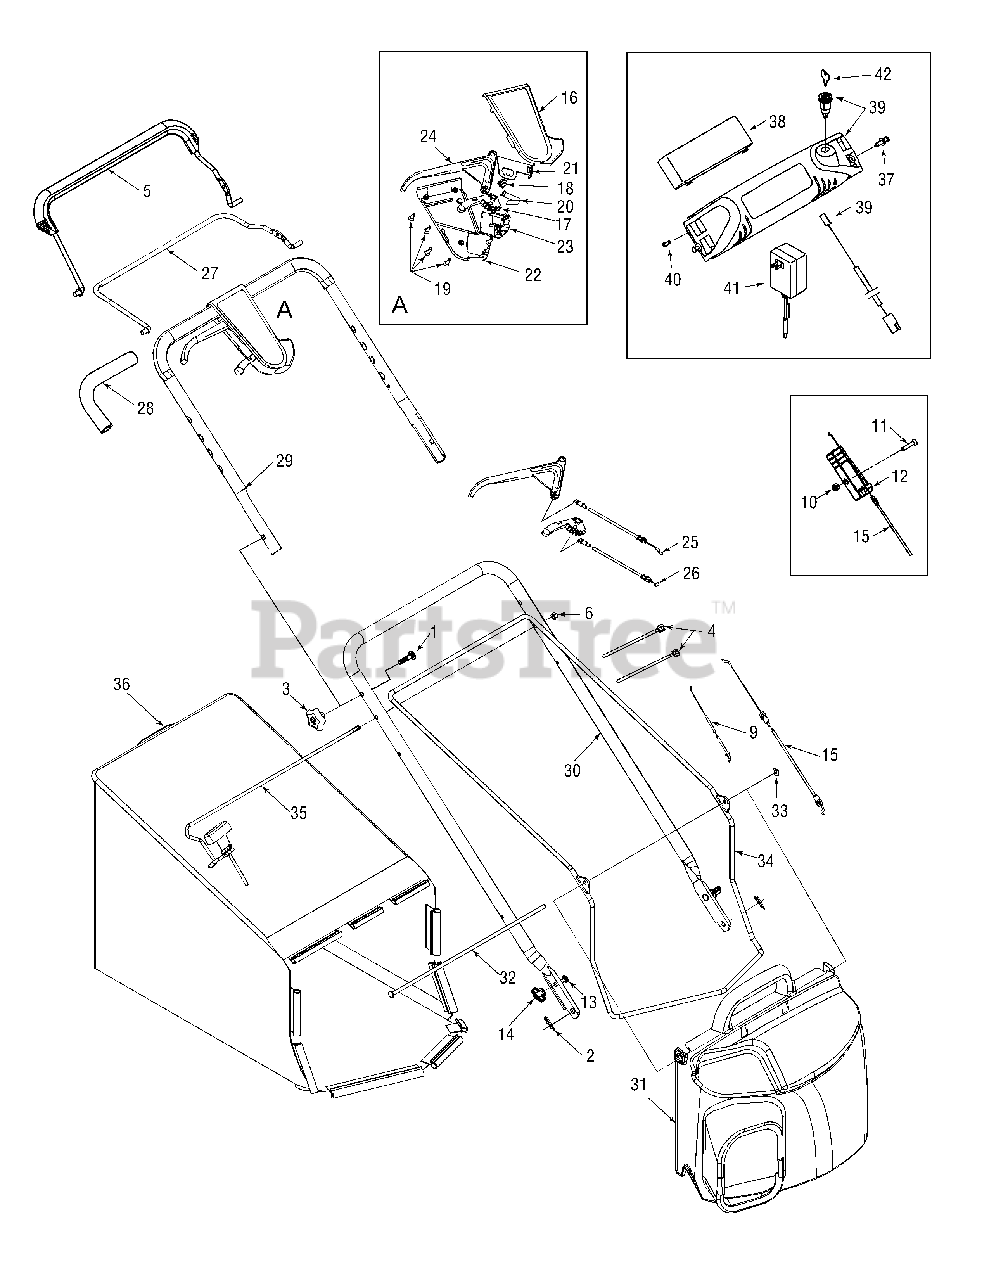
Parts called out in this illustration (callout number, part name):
1	Carriage Bolt 5/16-18 x 2.0
2	Int. Cotter Pin 5/16 DIA
4	Cable Tie
5	Control Bail Lever - Deluxe Black
6	Flg. Lock Nut 5/16-18 Gr. F Nylon
8	Cup. Wash. .265 ID x .75 OD x .062
9	Throttle Wire 60.0" Lg. Yel low
10	Hex Ins. Locknut 1/4-20
11	Mach. Screw 1/4-20 x 1.319
12	Cable Bracket
13	Carriage Bolt 1/4-20 x .75
14	Wing Nut
15	Control Cable 40.5" Lg.(B&S)
16	Control Cover
17	6 Speed Shift Lever
18	3 Tooth Rack Gear Insert
19	C-sunk Tap Screw #10 x .75
20	Shift Lever Spring
21	Rack Cable Bracket
22	Control Cover
23	Control Cover
24	Control Lever
25	Pulley Cable 53" Lg.
26	Clutch Cable - 53" Lg. Or ange
27	Control Bail Lever
28	Foam Grip
29	Upper Handle(w/Electric start only)
31	Grassbag Cover w/Label
32	Grasscatcher Pivot Rod
33	Push Cap
34	Grasscatcher Upper Frame
35	Grasscatcher Support Rod
38	12V Battery
39	Electric Starter Harness Ass'y
39	Cable Guide, Harness
40	Screw, #10-16 x .750
41	Battery Charger
